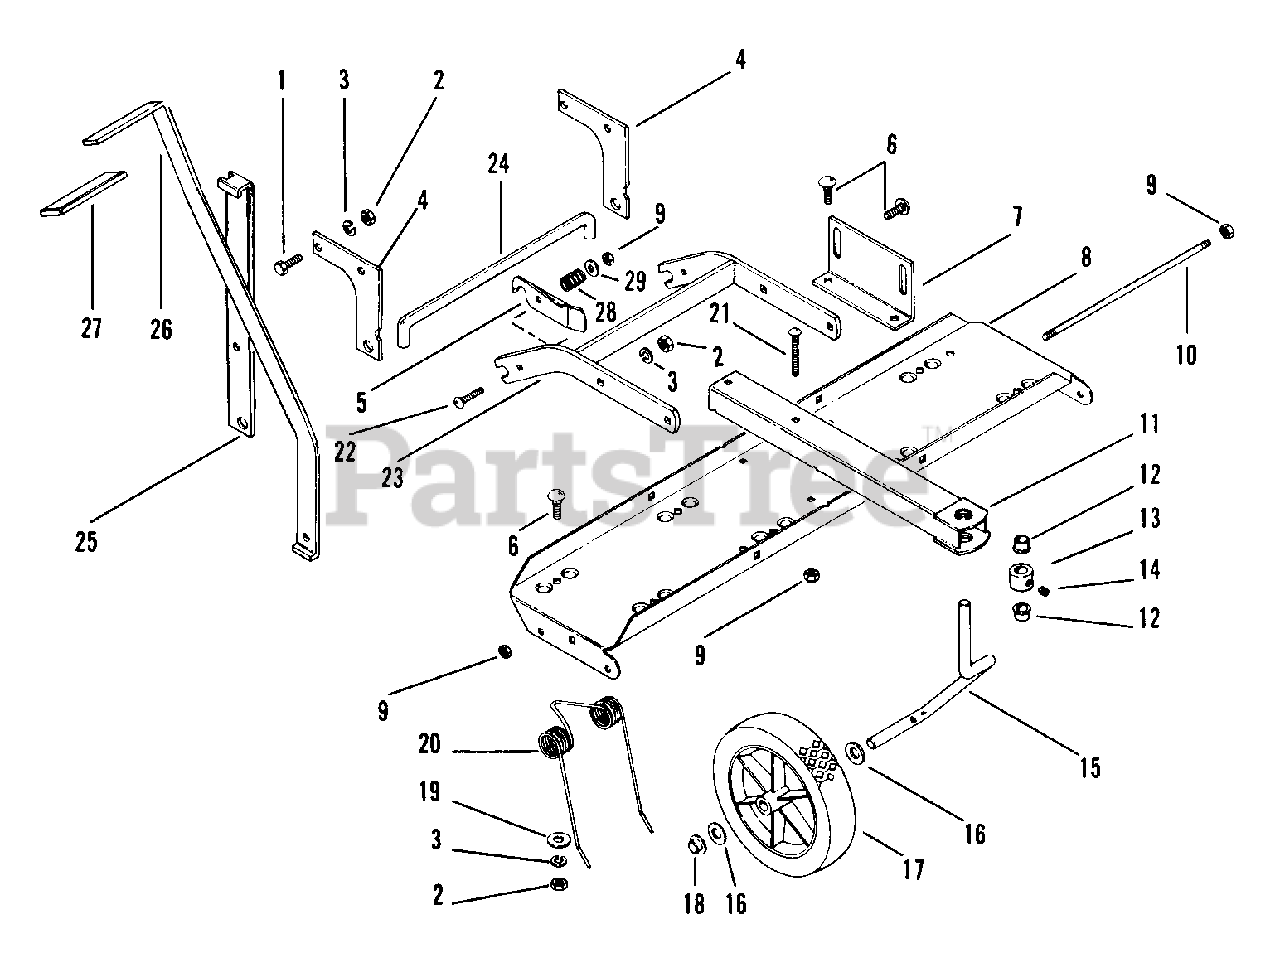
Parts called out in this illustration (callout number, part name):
1	BLT-HEX .31-18X1.00 PL GR 2
2	NUT-HEX .312-18
3	WSHR-LK .313X.078 PL MED
4	MOUNTING PLATE
5	AXLE LOCK
6	BLT-RDHDSQNK .31-18X1.00 PL
7	BRACKET-FRAME MOUNT
8	TRAY-TINE
9	NUT-LK TOP .250-20 PL
10	ROD-TINE
11	WHEEL SUPPORT ASSY
12	BSHG-FLG .500X.562X.687 NY
13	LOCKING COLLAR
14	SCR-SET .32-18X.38 SKHCUPNL OH
15	AXLE-WHEEL
16	WSHR-FL-STL .505X1.000X.062
17	WHL
18	CAP, .50 ROD YWZC
19	WSHR-FL-STL .328X1.0X.094 PL
20	SPRING TINE
21	BLT-RDHDSQNK .25-20X2.50 PL
22	BLT-RDHDSQNK .25-20X1.25 GR5PL
23	FRAME ASSY
24	ROD-MOUNTING
25	BAR-LOCK
26	LIFT HANDLE
27	GRIP-VINYL
28	SG-COMP .062X.462X.75
29	WSHR-FL-STL .250X.562X.049 PL
